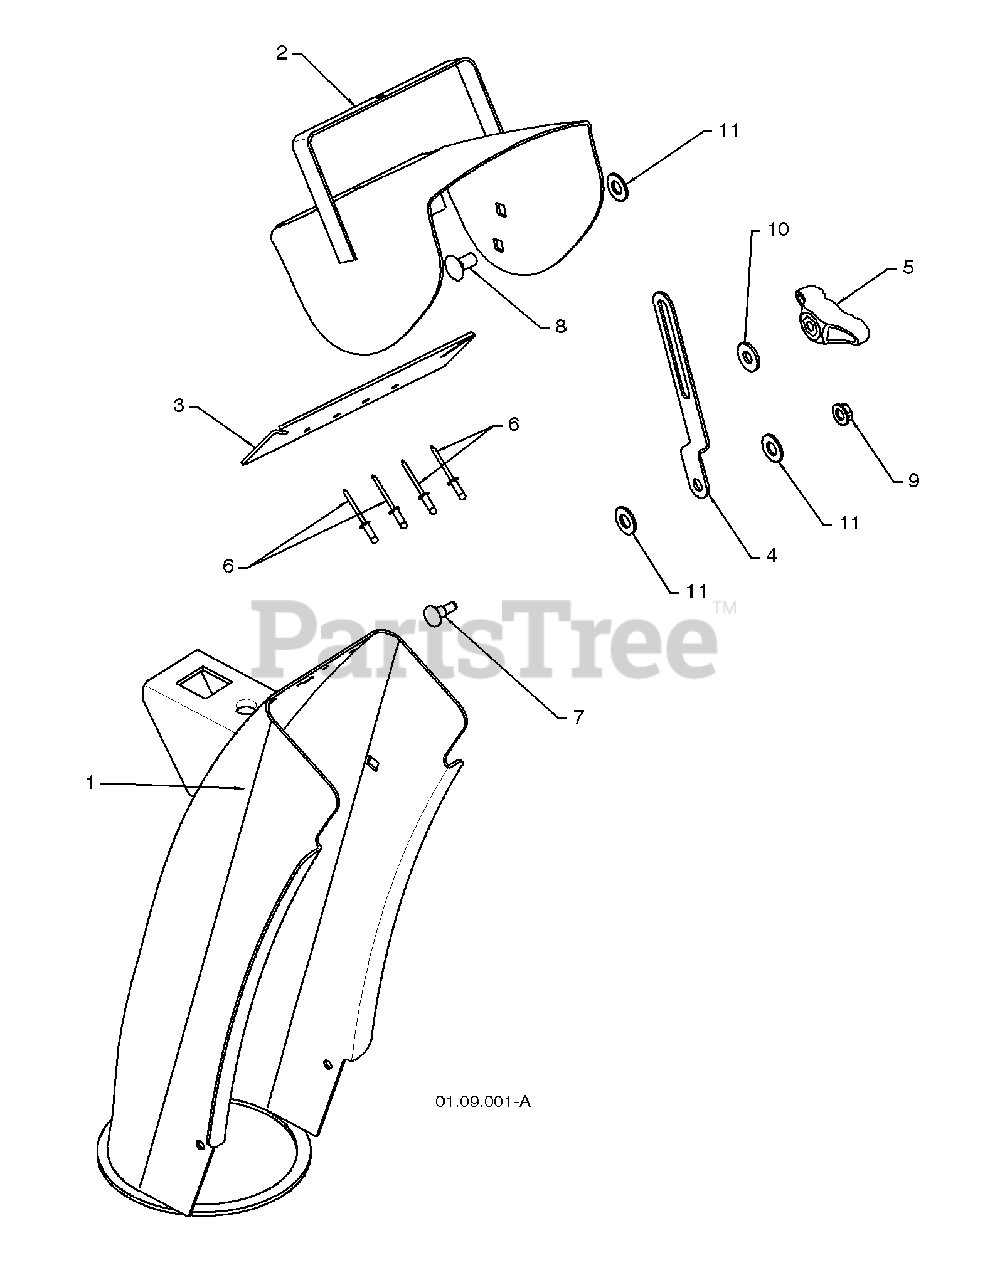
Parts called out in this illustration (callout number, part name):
1	CHUTE WELDMENT
2	DEFLECTOR WELDMENT
3	DEFLECTOR SEAL
4	STRAP
5	KNOB BLACK
7	SHOULDER BOLT 1/4-20 X .704
8	CARRIAGE BOLT 5/16-18 X .625
9	NUT 1/4-20
11	PLASTIC WASHER
